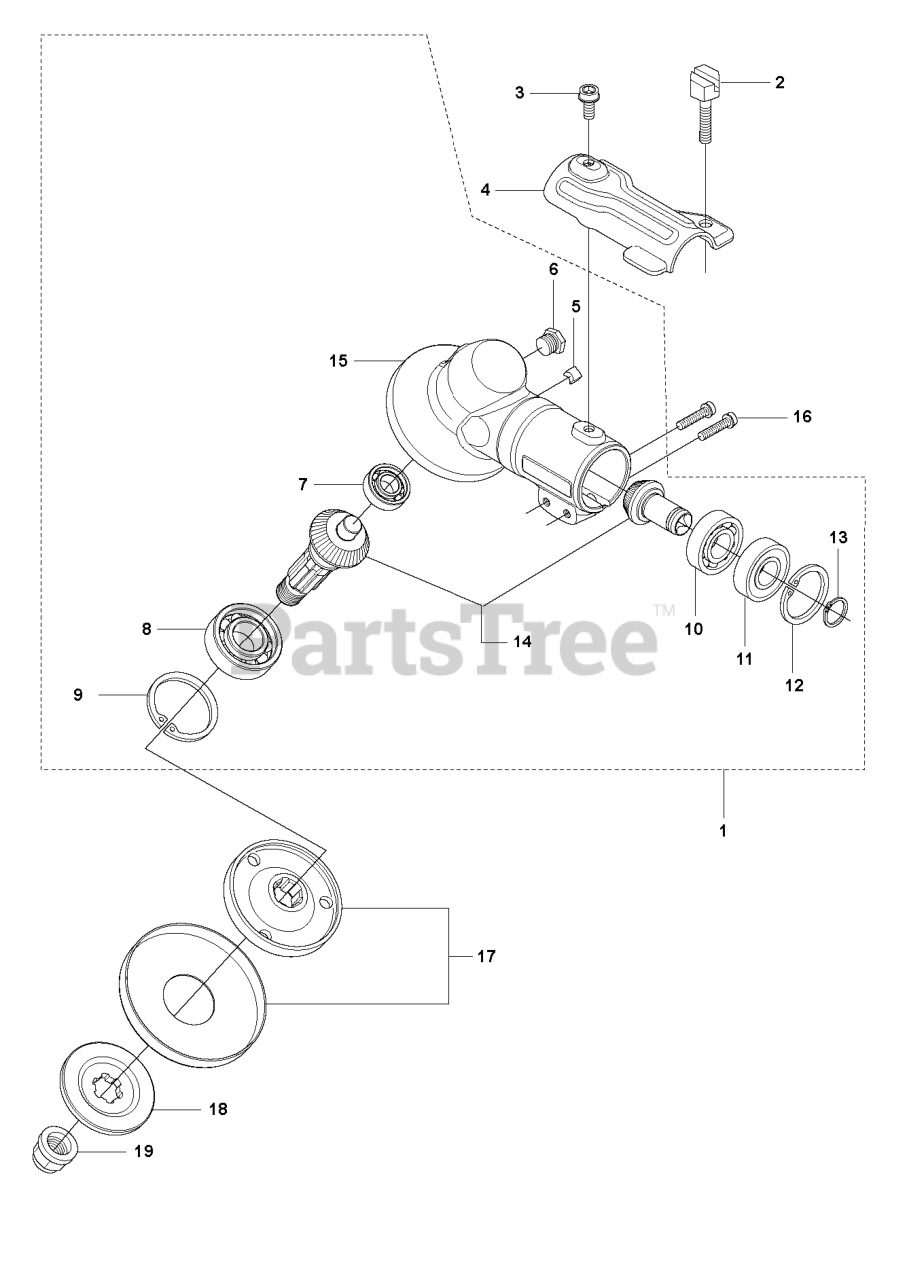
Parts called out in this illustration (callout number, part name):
1	GEAR CASE SET
3	SCREW
4	RP HOLDER
7	BALL BEARING 24X9X1/609ZR
8	BALL BEARING
9	RETAINING RING
10	BALL BEARING
11	BALL BEARING
12	RETAINING RING SGH 28
13	SEEGER CLIP
14	SPARE PARTS KIT
17	CARRIER
18	RP FLANGE
19	BLADE NUT
